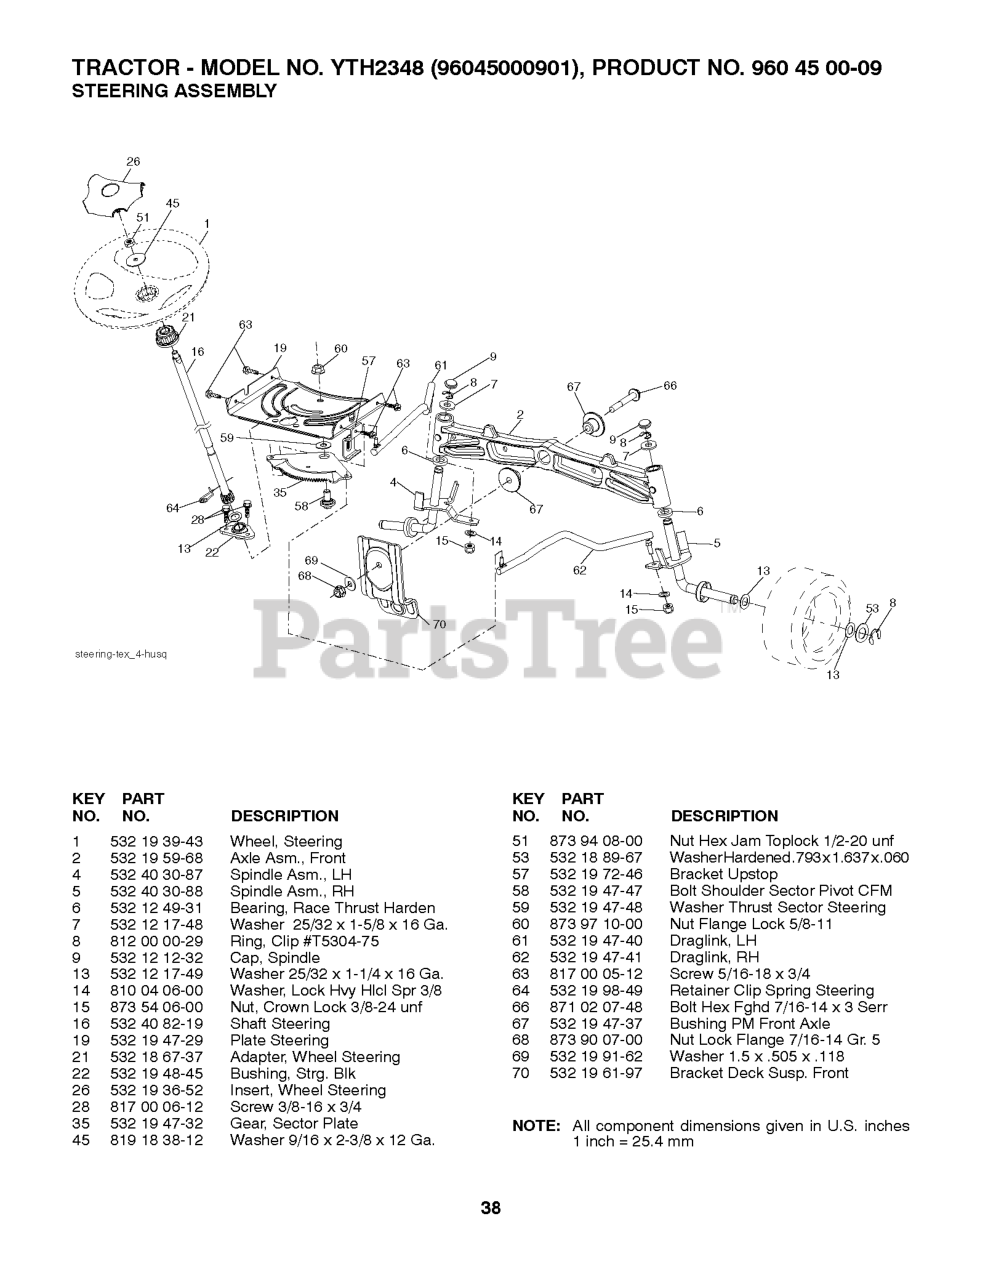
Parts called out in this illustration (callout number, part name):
1	WHEEL.STEERING.LEGEND2.GRY
2	AXLE.CAST.IRON
4	SPINDLE.WELDED.LH.15"TEX
5	SPINDLE.WELDED.RH.15"T
6	THRUST WASHER
9	CAP.SPINDLE.BLACK
14	WASHER, LOCK 3/8
15	NUT CROWNLOCK 3/8-24
16	SHAFT, STEERING
19	PLATE.STEER.DDL.NLT/NG
21	ADAPTER, WHEEL STNG..
22	BUSHING.ASM.STEERING.A
26	INSERT.CAP.STRG.WH.GRAY
28	SCREW, 3/8-16X3/4
35	GEAR.SECTOR.PLATE.DDL.
45	WASHER 9/16"ID, 2 3/8"OD
51	NUT.HEX.1/2-20
53	WASHER.HARDENED
57	BRKT.UPSTOP.GT/LT.TEX
58	BOLT.SHOULDER.SECTOR.P
59	WASHER.THURST.SECTOR.S
60	NUT FLANGE LOCK 5/8-11
61	DRAGLINK.LH.BALLSTUD.D
62	DRAGLINK.RH.BALLSTUD.D
63	SCREW
64	RETAINER.CLIP.SPRING.S
66	BOLT HEX FGHD 7/16-14 X 3 SERR
67	BUSHING.PM.FRONT AXLE
68	NUT.LOCK.FLANGE.7/16
69	WASHER.1.5X.505X.118
70	BRKT.DECK.SUSPENSION.F
